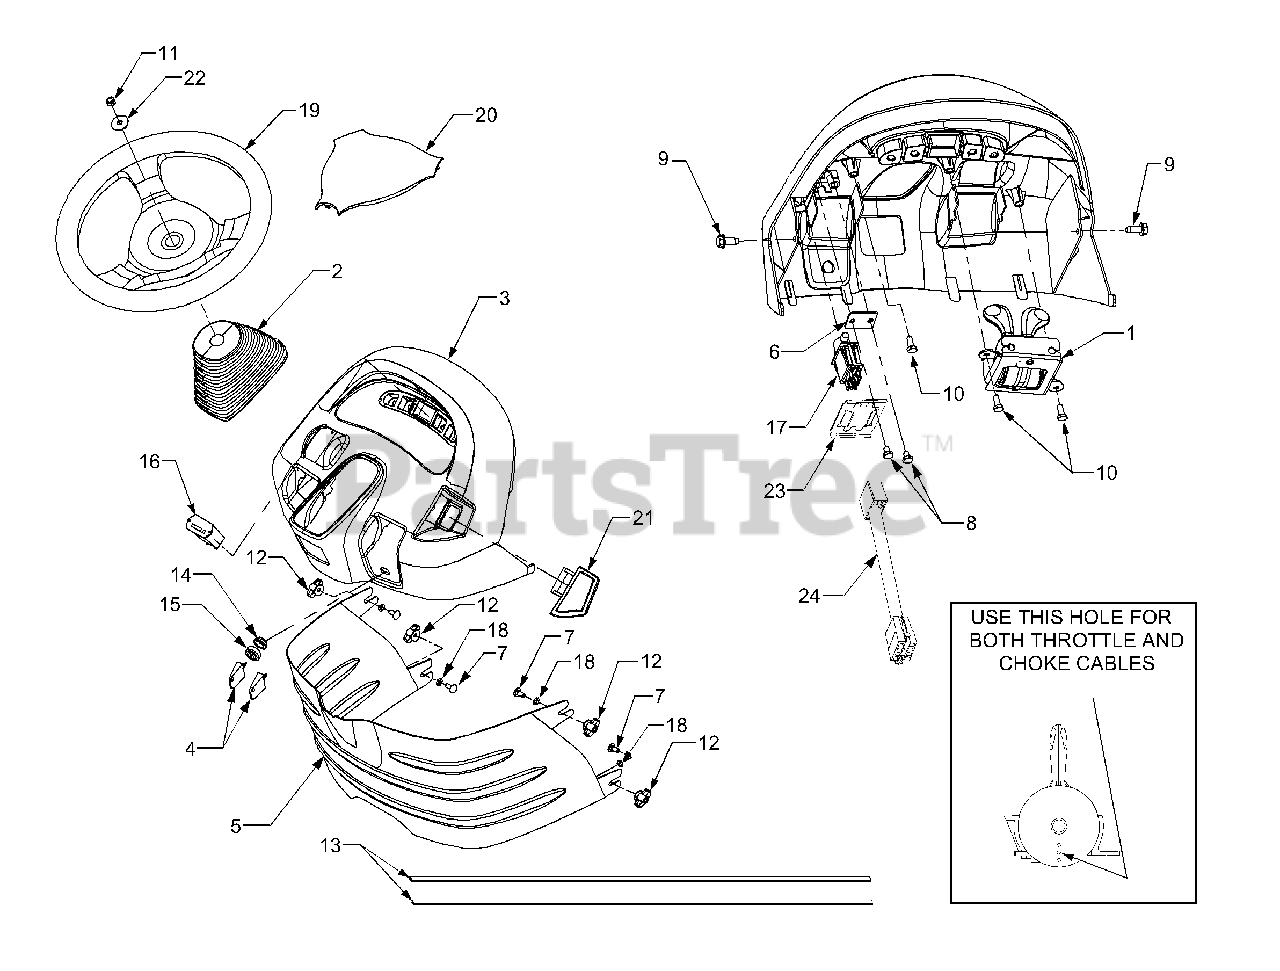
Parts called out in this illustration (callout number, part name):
1	Control Assembly, Throttle/Choke
2	Boot, Tilt Steer
3	Dash Panel
4	Key, Ignition (Set of 2)
7	Carriage Bolt, 1/4-20 x .62
8	Screw, Hex Cap 1/4-20 x .375 GR5
9	Screw, Hex Wash. Hd. Tapp 5/16-18 x .75
10	Screw, Hex Cap 1/4-20 x .50 GR5
11	Nut, Hex Lock, 5/16-24
12	Wing Nut, 1/4-20 w/Bell Washer
13	Seal, Screen
14	Nut, Ignition Switch, 5/8-32
15	Cap, Ignition Switch
16	Hour Meter
17	Switch, PTO
18	Nut, Push
19	Steering Wheel
20	Cover, Steering Wheel
21	Handle, PTO Switch
22	Washer, Flat, .34 x 1.5 x .10
23	Bracket, PTO Switch Retainer
24	Harness, PTO Adapter
